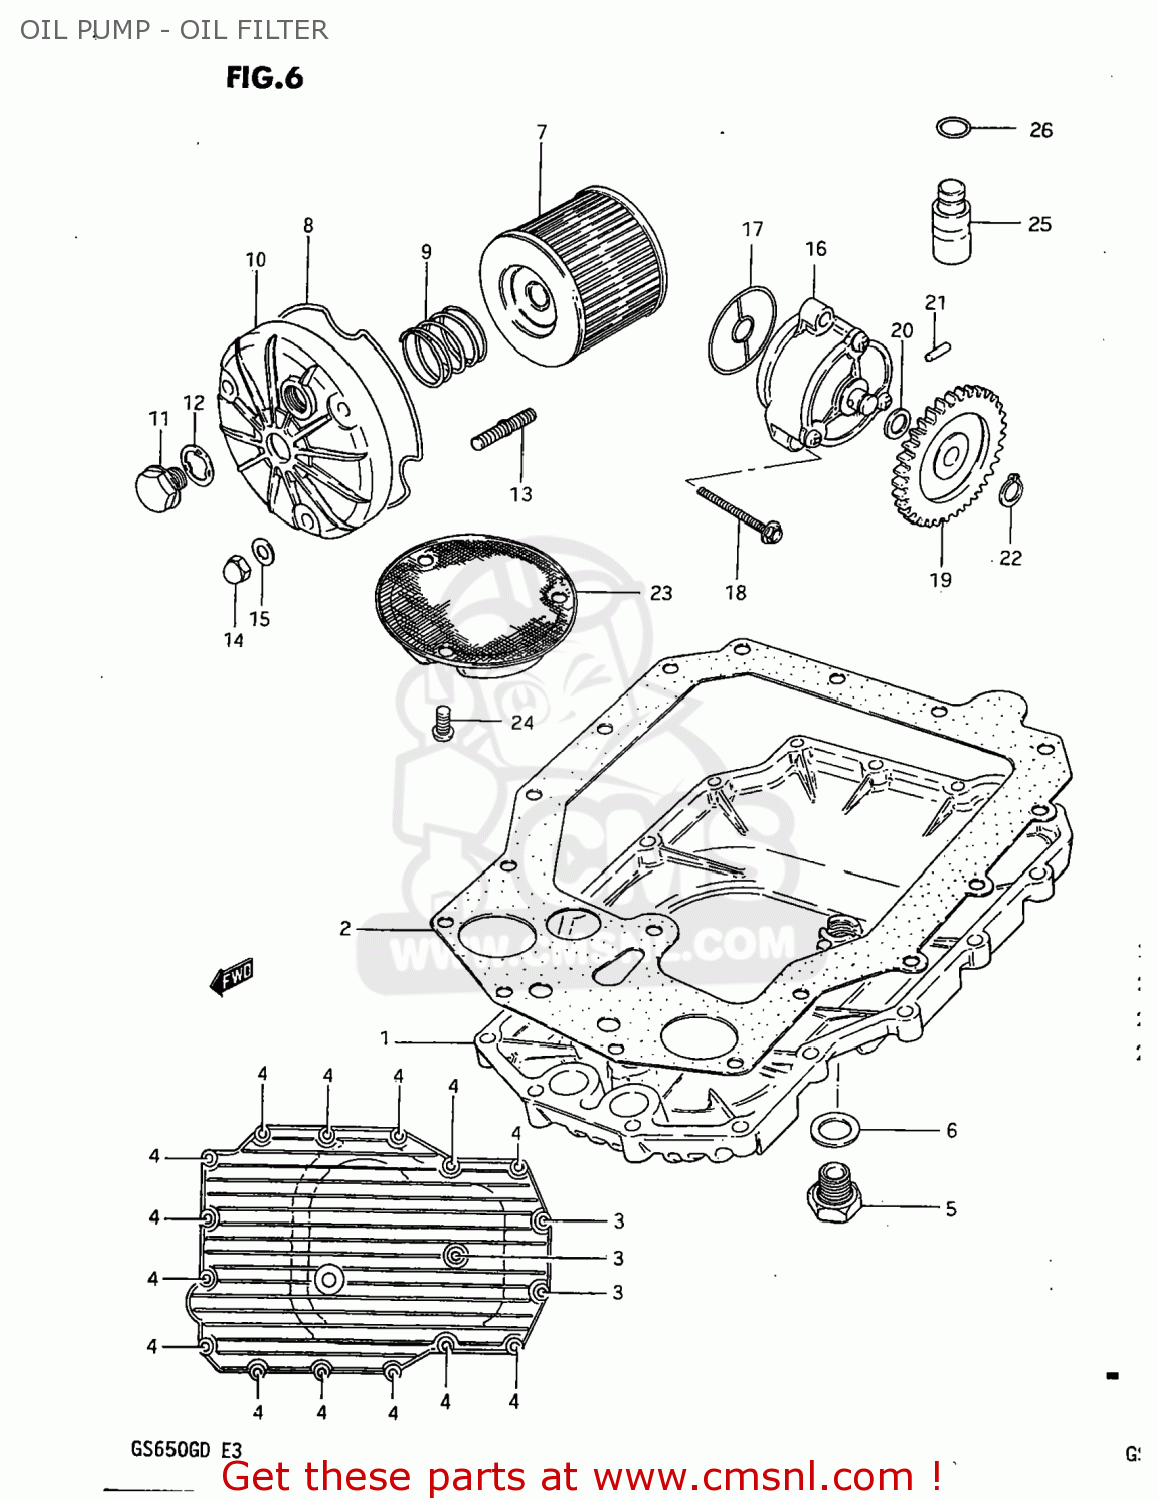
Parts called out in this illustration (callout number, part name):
1	PAN,OIL
2	GASKET,OIL PAN (MCA)
3	BOLT
4	BOLT
5	PLUG
6	GASKET(14X19.2X2) (NAS)
7	FILTER ASSY,ENGINE OIL
8	O RING,OIL FILTER CHAMBER CAP
9	SPRING
10	CAP,OIL FILTER
11	PLUG (14X12)
12	GASKET(14X19.2X2) (NAS)
13	STUD 6X20
14	NUT
15	WASHER
16	PUMP ASSEMBLY,ENGINE OIL
17	O-RING,OIL PUMP
18	BOLT
19	GEAR,OIL PUMP DRIVEN
20	SHIM
21	PIN(4X15.8)
22	CIRCLIP
23	STRAINER,ENGINE OIL
24	SCREW 6X12
25	REGULATOR ASSEMBLY,ENGINE
26	O-RING
